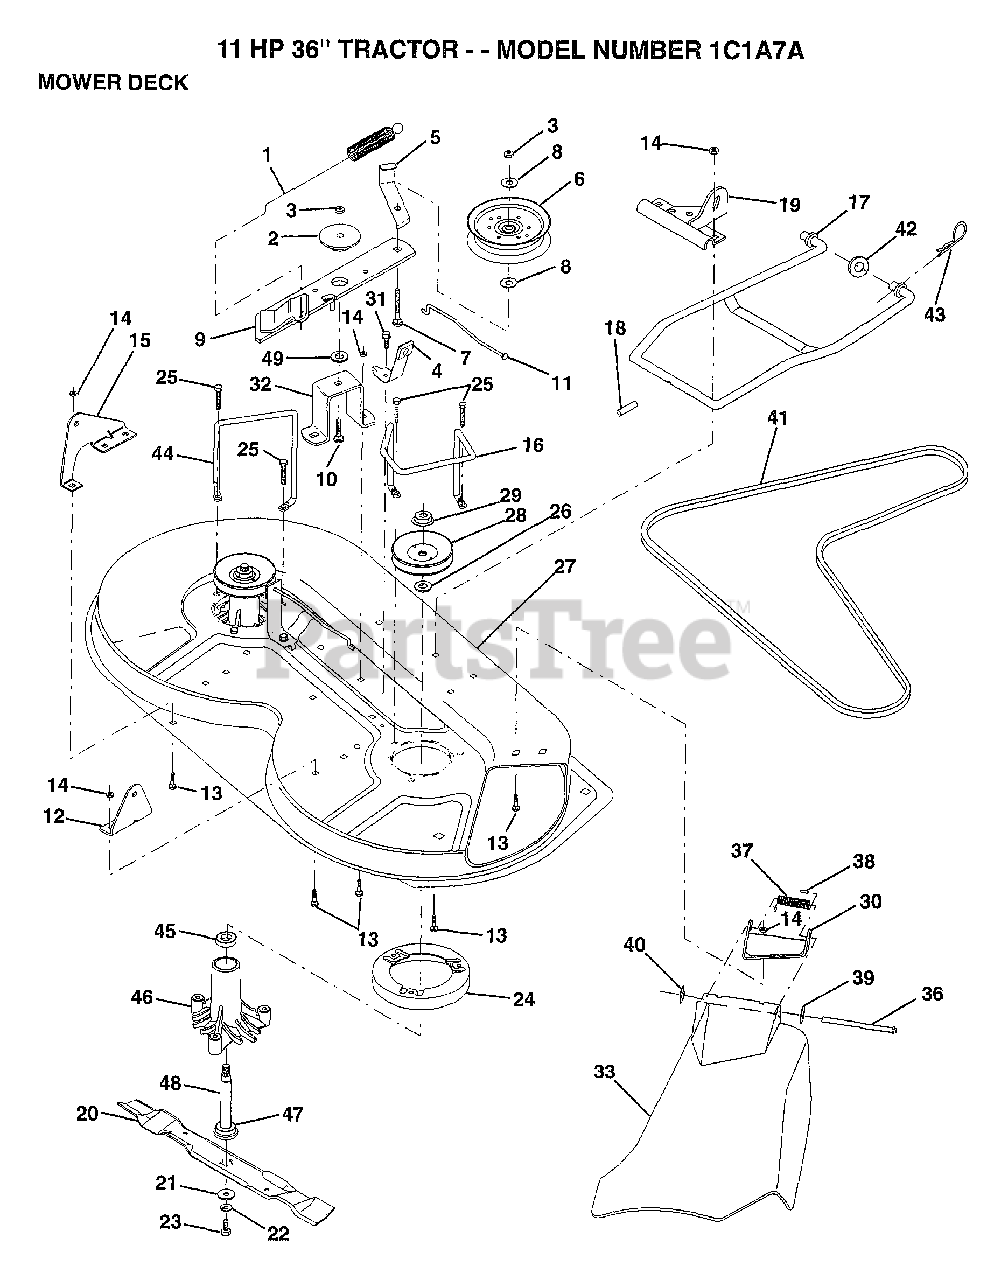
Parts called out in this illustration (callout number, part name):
1	SPRING CLUTCH MWR
2	SPACER RETAINER
3	NUT
4	BRAKE ASM
5	IDLER BELT GUIDE
6	PULLEY IDLER
7	BOLT CARRIAGE
8	WASHER
10	BOLT.3/8-14X1.25
11	BRAKE ROD
12	"BRKT,LIFT REAR"
13	BOLT
14	NUT
15	"BRKT,LIFT REAR LH"
17	MOWER LINK STAB
18	"PIN,GROOVE"
19	"BRKT,LINK STABILI"
20	"BLADE MULCH 36"""
21	WASHER.HARD.BLADE
23	BLADE BOLT
24	STRIPPER RND MWR
26	WASHER
31	SCREW LT
32	"SUPT,IDLER ARM"
36	HINGE ROD
37	SPRING TORSION
38	CAP-SLEEVE LT
39	WASHER
40	NUT PUSH M
41	V-BELT.PRIM.78.5.
43	RETAINER.SPRING
44	KEEPER BELT LH
45	BEARING
46	HSG ASM MANDREL
47	BEARING.BALL
49	HARDENED WASHER
